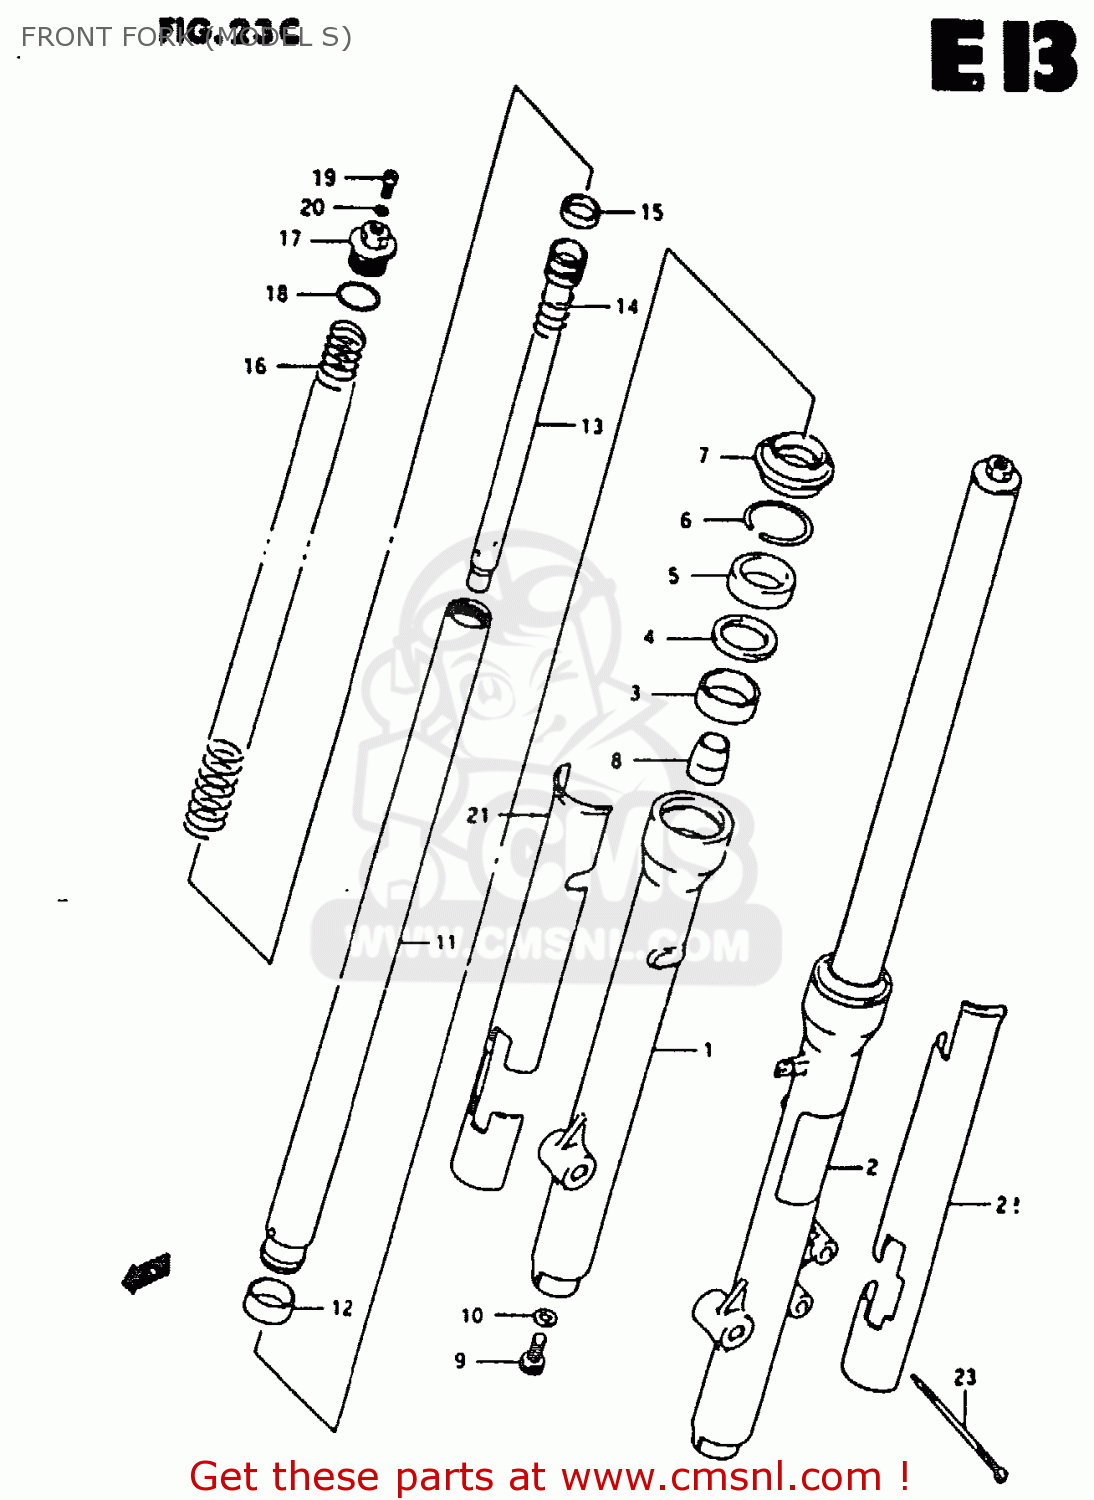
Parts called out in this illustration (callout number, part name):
1	TUBE,OUTER,R
2	TUBE,OUTER,L
3	BUSH,GUIDE
4	SPACER,SEAL
5	SEAL,OIL 35X48X11
6	RING,OIL SEAL STOPPER
7	SEAL,DUST
8	PIECE,OIL LOCK
9	BOLT(8X27)
10	GASKET (NAS)
11	TUBE,INNER
12	PISTON
13	SEAT,UNDER
14	SPRING,REBOUND
15	RING,PISTON
16	SPRING,UNDER
17	BOLT,FORK
18	O RING
19	BOLT,PLUG
20	O RING
21	PROTECTOR,FR FORK,R
22	PROTECTOR,FR FORK,L
23	CLAMP
24	CLAMP
25	SPRING
26	PROTECTOR,FR FORK,L
27	CLAMP
28	SPRING,FRONT FORK
